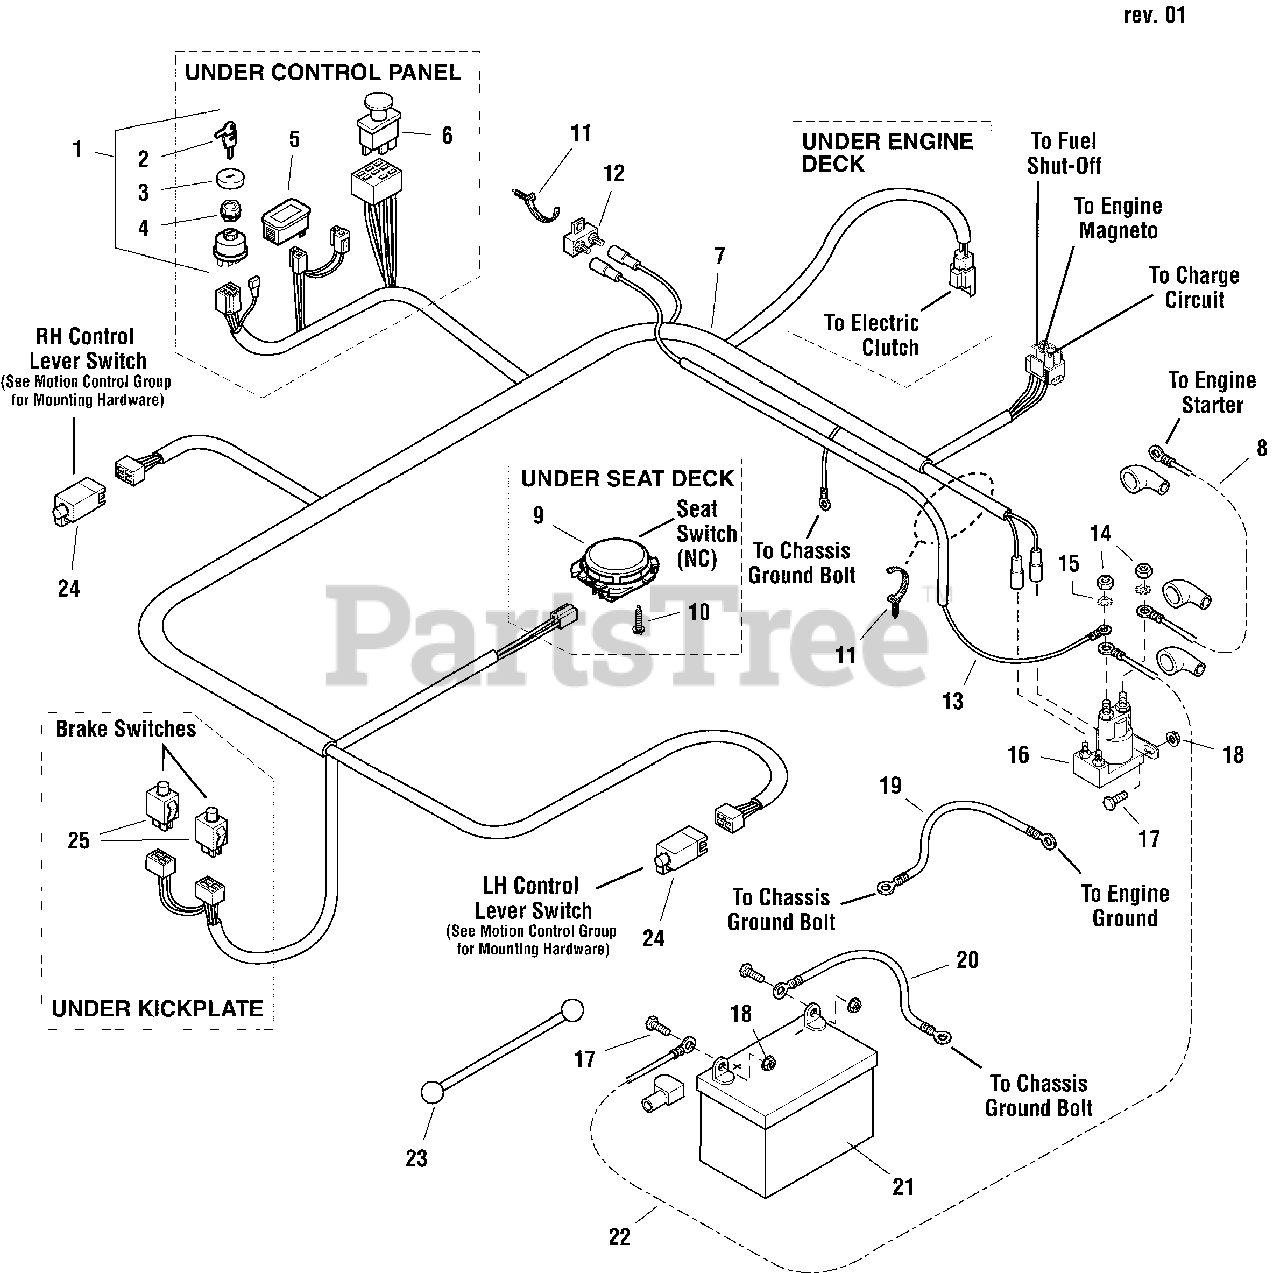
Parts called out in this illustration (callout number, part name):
1	SWITCH, IGNITION,
2	KEY, Ignition Molded
4	PLASTIC NUT
5	HOUR METER, DIGITAL
6	SWITCH, PTO
7	MAIN HARNESS ASSEMBLY
8	CABLE, #6 X 15" LONG, RING TERMINAL
9	SWITCH, SEAT, GRAY, NC
10	BOLT, HEX WASHER HEAD PLASTITE, 1/4 X 1/2
11	CABLE TIE, PUSH MOUNT
12	CIRCUIT BREAKER, 20A
13	CRICUIT BREAKER WIRE ASSEMBLY
14	NUT, HEX JAM, 5/16-24
15	WASHER, LIGHT LOCK, 5/16
16	SOLENOID
17	BOLT, 1/4-20 X 3/4
18	NUT, HEX SERRATED FLANGE, 1/4-20
19	CABLE, #6 X 10" LONG, RING TERMINAL
20	CABLE, #6 X 22" LONG, RING TERMINAL
21	BATTERY, 12 VOLT
22	CABLE, #6 X 30" LONG, RING TERMINAL
23	STRAP, BATTERY, 14 LONG, RUBBER
24	SWITCH, PLUNGER, N.O./N.C.
25	SWITCH, DP NO/NC SNAP-IN
